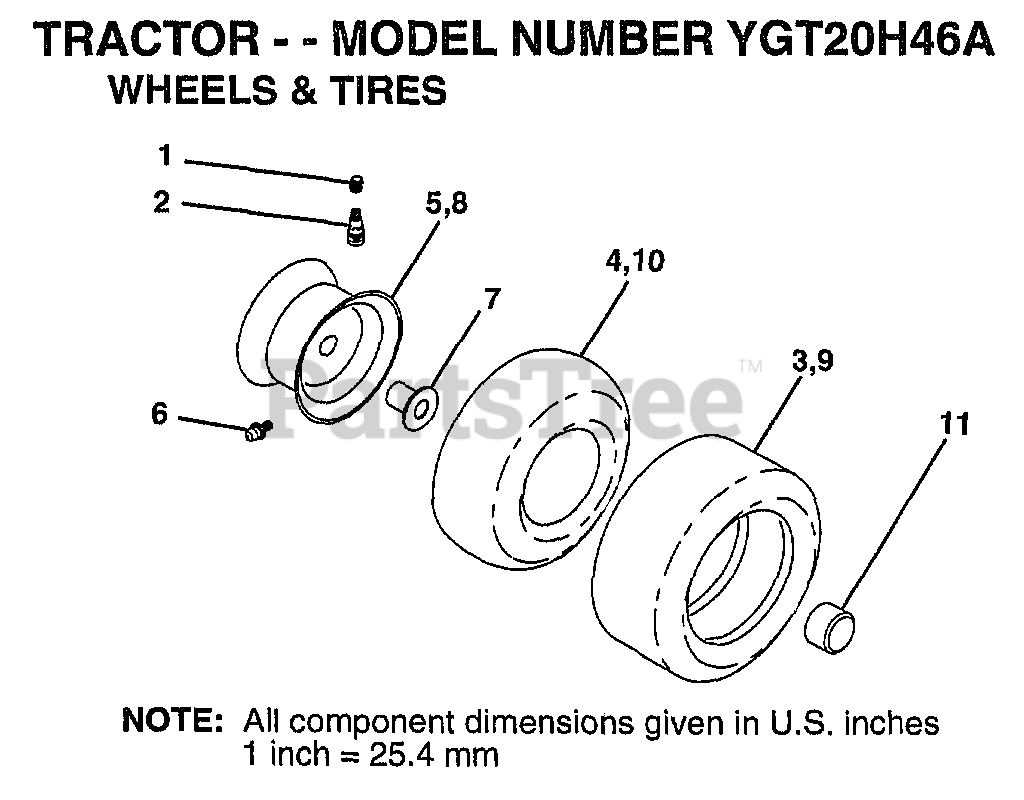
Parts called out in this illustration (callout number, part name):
1	VALVE CAP
2	VALVE STEM LT
4	TUBE.5.3/4.5/6
5	"RIM ASM 8"" FRT"
6	FITTING LT
7	"FLANGE, BEARING"
8	RIM.REAR.
9	TIRE.R.23X9.5-12
10	TUBE.23X8/10-12
11	HUB CAP
